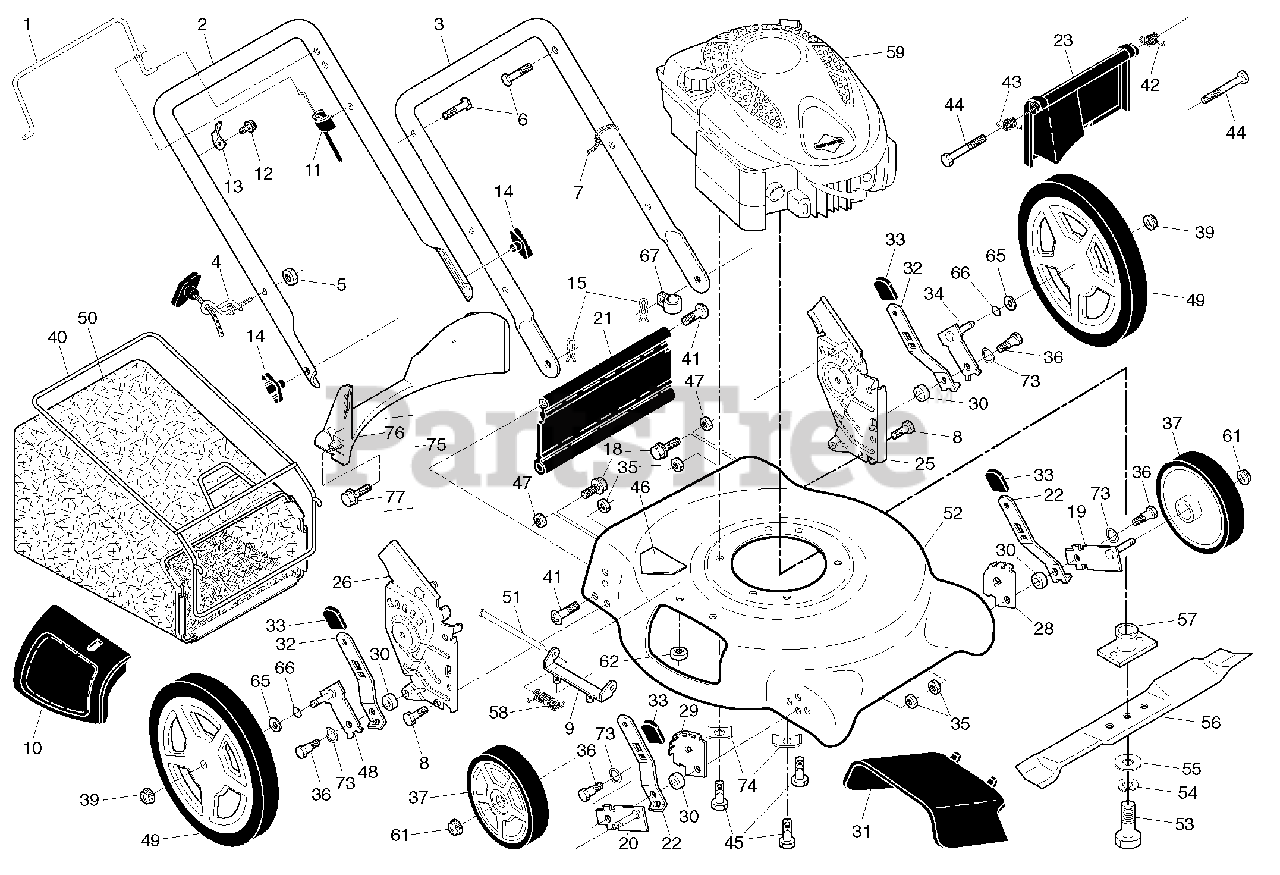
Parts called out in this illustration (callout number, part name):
1	Control Bar
2	Upper Handle
3	Lower Handle
4	Rope Guide
6	Handle Bolt
7	Wire Tie
8	Bolt, Hex Head 5/16-18 x 3/4
9	Hinge Bracket
10	Mulcher Door
11	Engine Zone Control Cable
12	Hex Washer Head Screw #10-24 x 1/2
13	Up-Stop Bracket
14	Handle Knob
15	Hairpin Cotter
18	Screw
19	Axle Arm Assembly, Front, LH
20	Axle Arm Assembly, Front, RH
21	Kit, Rear Skirt
22	Selector Spring, Front
23	Rear Door Assembly
25	Handle Bracket, LH
26	Handle Bracket, RH
28	Wheel Adjusting Bracket, Front, LH
29	Wheel Adjusting Bracket, Front, RH
30	Spacer
31	Discharge Deflector
32	Selector Spring, Rear
33	Selector Knob
34	Axle Arm Assembly, Rear, LH
35	Locknut, Hex 5/16-18
36	Shoulder Bolt 5/16-18
37	Wheel & Tire Assembly, Front 7 x 1-3/4
39	Nut, Hex
40	Frame, Grassbag
41	Screw, Hinge
42	Spring, LH
43	Spring, RH
44	Bolt, Rear Door
45	Hex Head Thread Rolling Screw 3/8-16 x 1
46	Danger Decal
47	Nut, Hex
48	Axle Arm Assembly, Rear, RH
49	Wheel & Tire Assembly, Rear 12 x 1-3/4
51	Hinge Rod
52	Kit, Housing
53	Screw, Hex Head, Grade 8 3/8-24 x 1-3/8
54	Helical Lockwasher
55	Hardened Washer
56	21" Blade
57	Blade Adapter
58	Hinge Spring
61	Flanged Locknut
62	Nut, Hex
65	Washer, Flat
66	O-Ring
67	Clip, Cable
73	Washer, Curved, Cylindrical
74	Washer, Special, Engine
75	Kit, Rear Baffle
76	Baffle, Rear
77	Screw, Rear Baffle
77	Operator's Manual, English
77	Operator's Manual, French
77	Repair Parts Manual
